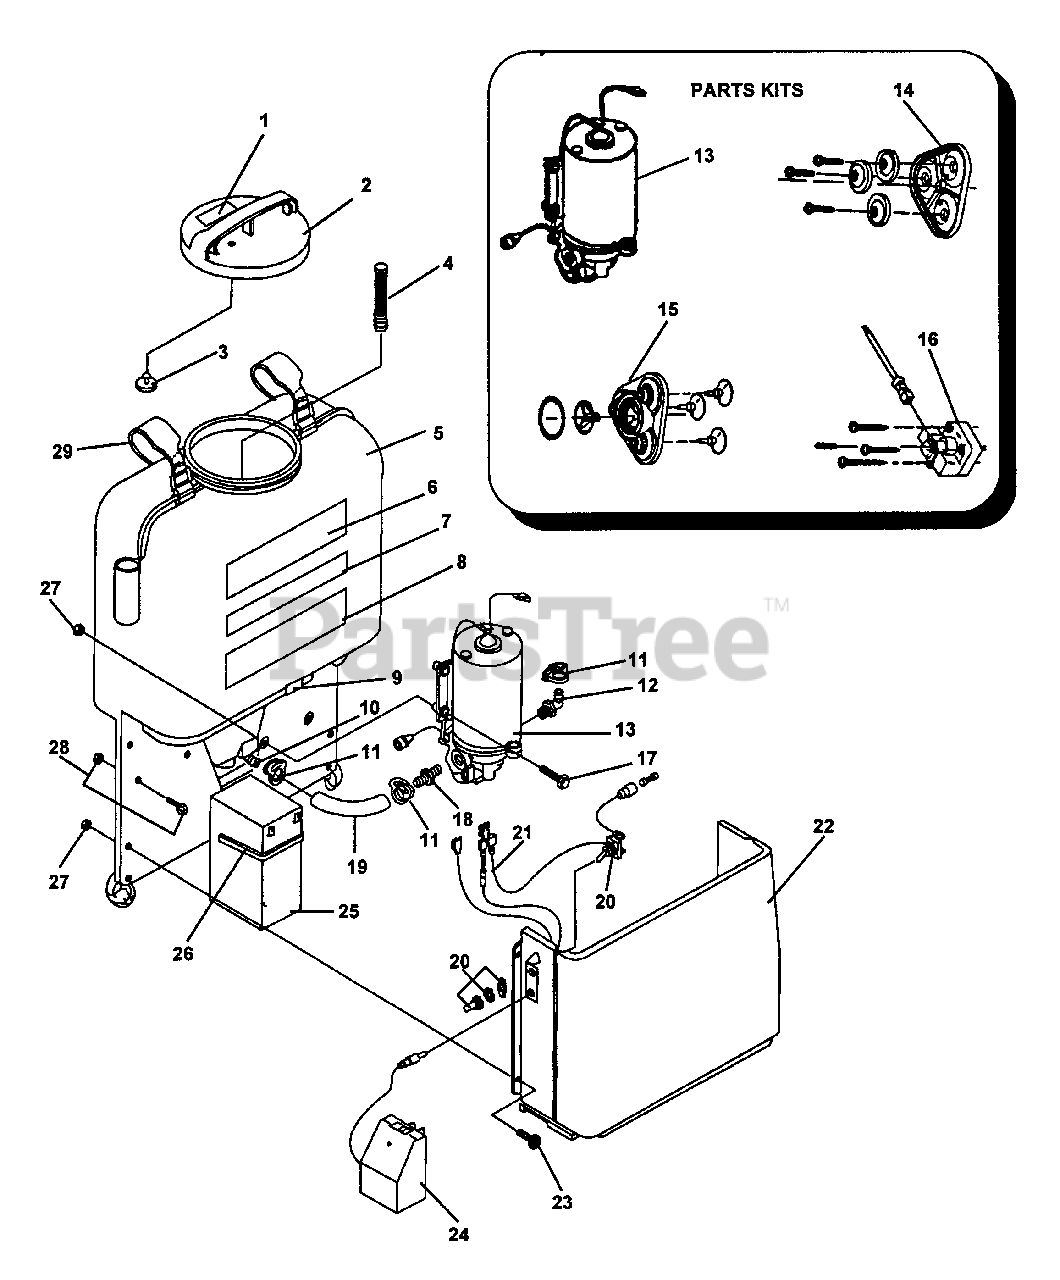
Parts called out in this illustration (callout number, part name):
1	LABEL - WARNING
3	VALVE, CHECK
4	FILTER, TANK
6	LABEL - ECHO
7	LABEL - SERIAL NUMBER
8	LABEL - LARGE WARNING
9	LABEL - BATTERY WARNING
10	BARB FITTING, TANK - 90 Deg.
11	CLAMP, HOSE
12	FITTING, BARB - 90 DEG. X 3/8 NPT
13	PUMP - 12 VOLT
14	DIAPHRAGM KIT
15	VALVE KIT
16	PRESSURE SWITCH KIT
17	BOLTS - 8 X 1-1/4"
18	FITTING - 3/8 NPT
19	HOSE - 3/8 I.D. PUMP TO TANK
20	SWITCH KIT
21	WIRING HARNESS
22	COVER
23	BOLTS - 8 X 1-1/4"
24	CHARGER, BATTERY - 12 VOLT
25	BATTERY - 12 VOLT
26	STRAP, BATTERY
27	NUTS, COVER #8
28	EYEBOLT & NUT, BATTERY TIE DOWN
29	HARNESS ASSY
